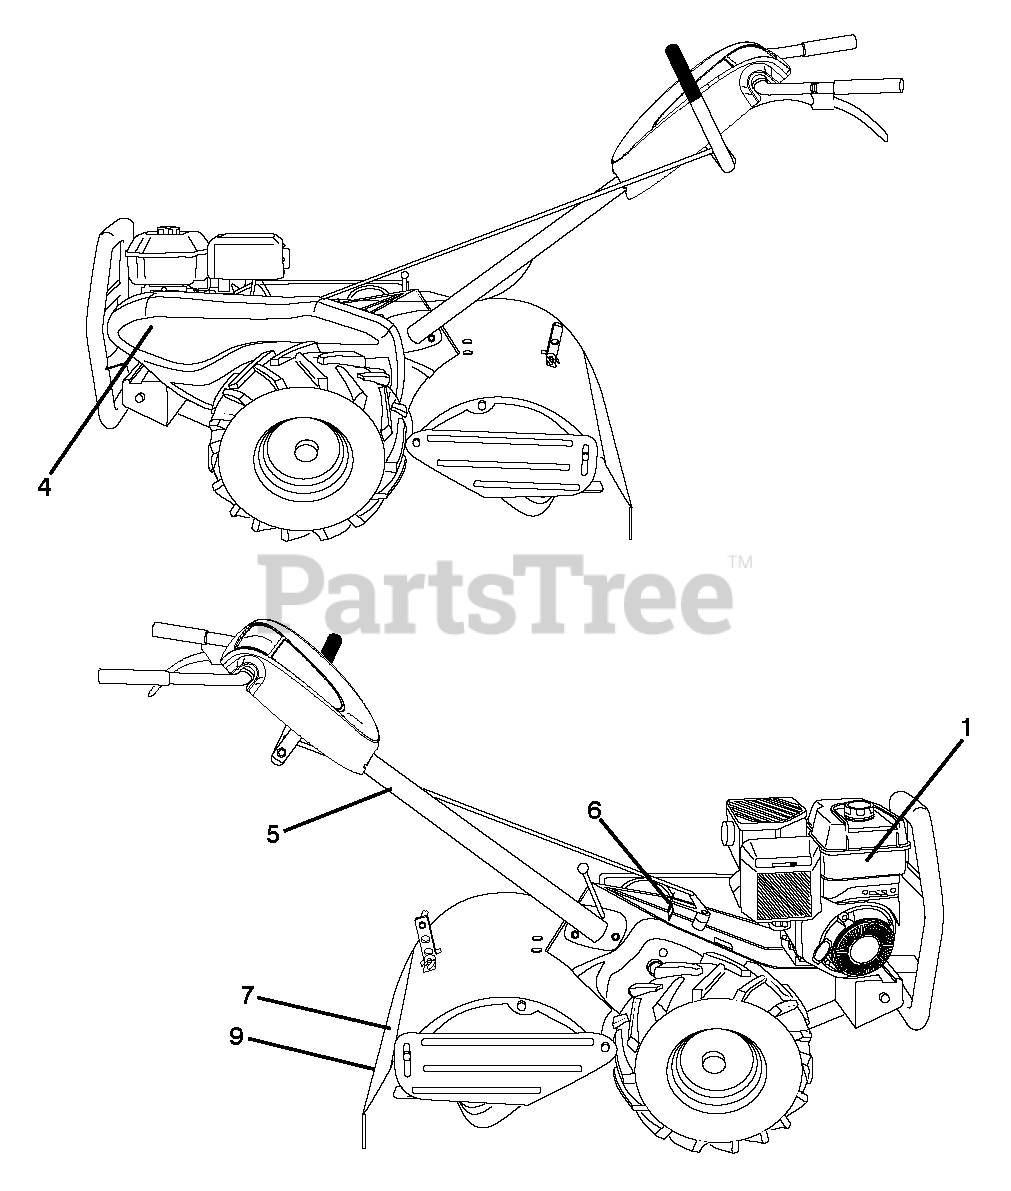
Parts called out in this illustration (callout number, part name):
1	Decal, B&S 900 TANK REF 276991
5	DECAL TI
6	DECAL.SHIFT.INDICATOR.TILLER
7	DECAL WARNING
